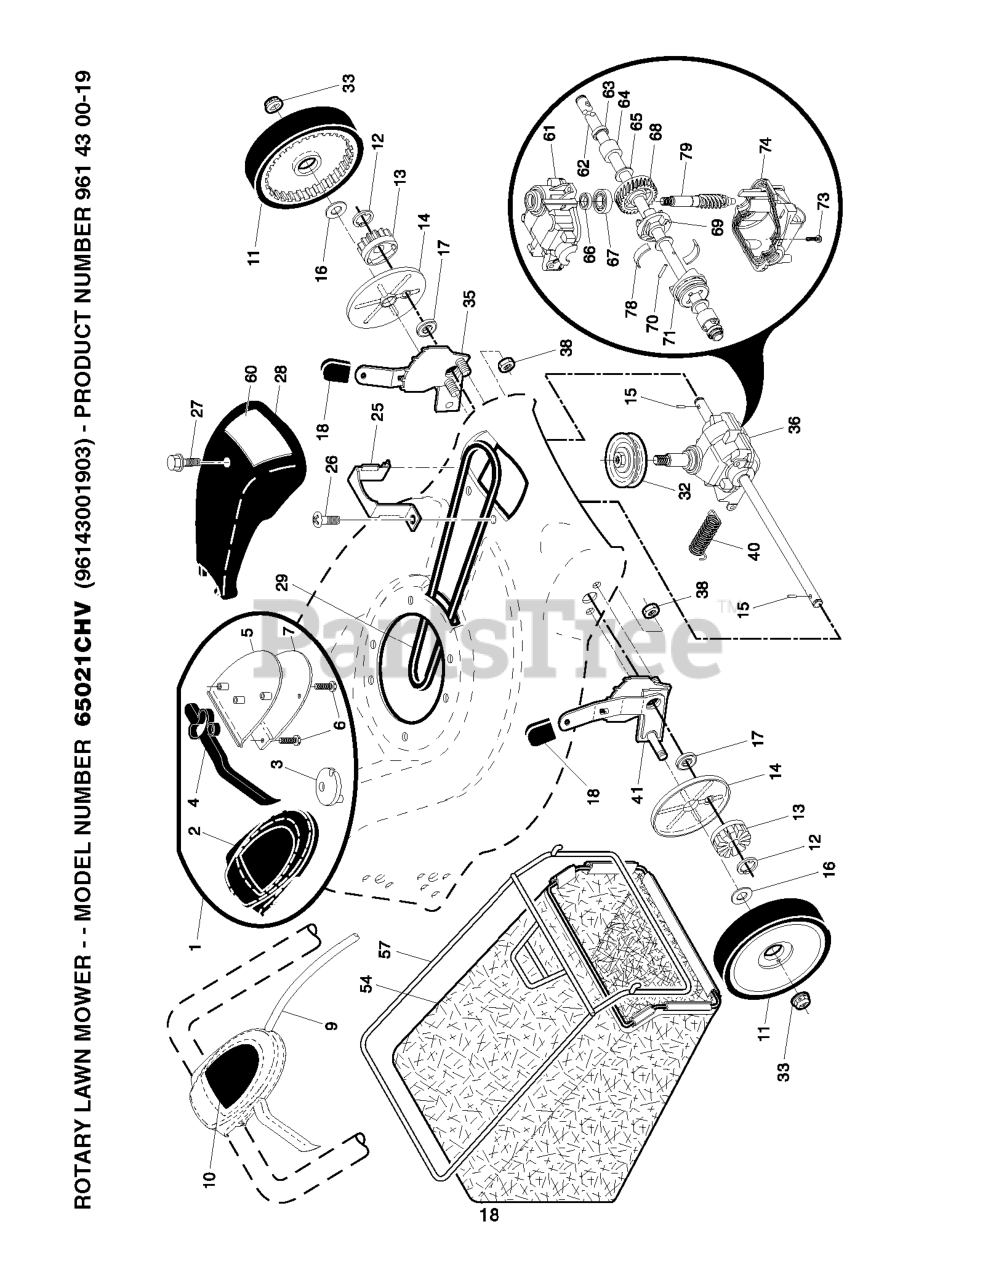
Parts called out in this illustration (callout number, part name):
1	DRIVE CONTROL ASSEMBLY (INCLUD
2	COVER TOP AUTO WALK CONTROL
3	PULLEY
4	LEVER, AUTOWALK DRIVE CONTROL
5	COVER BOTTOM AUTO WLK CONTROL
6	SCREW, PHILLIPS HEAD 10 X 5/8
7	BRACKET.DRIVE.CONTROL.MOUNT.BL
9	CABLE ASSEMBLY, DRIVE
10	DECAL, DRIVE
11	WHEEL.8X1.75.H3SPK.RAD3.GY.BU3
12	E-RING 7/16 RE
13	PINION.14.TEETH.FGD
14	COVER.DUST.WHEEL
15	PAWL.DRIVE
16	WASHER FLUT
17	BEARING ASM
18	KNOB.DELUXE.GRAY
25	BELT KEEPER
27	SCREW, HEX HD TAPPING #10-24 1
28	COVER.DR.21.FWGD/B&S.GRAY
29	BELT.DRIVE.FG
32	RP PULLEY.DRIVE.EZ
33	NUT.HEX.FLANGE.3/8-16.LO(3 2)
35	WHEEL ADJ KIT LH
36	TRANSMISSION.21.FGD.HT.VST
38	LOCKNUT.NYLOC.1/4-20
41	WHEEL ADJ KIT RH
54	GBAG.34710247.SILVER.H
57	FRAME, GRASSBAG
60	DECAL DRIVE COVER
61	CASE.UPPER.00254(SERVICE)
62	SHAFT OUTPUT (12289)
63	SEAL.OUTPUT.SHAFT
66	SEAL INPUT SHAFT
68	GEAR 28 TEETH 36208
69	FIXED DOG CLUTCH
70	PIN.3.50.33733
71	MOVEABLE DOG CLUTCH
74	CASE.BOTTOM.
78	SPRING LEAF
79	SHAFT WORM
